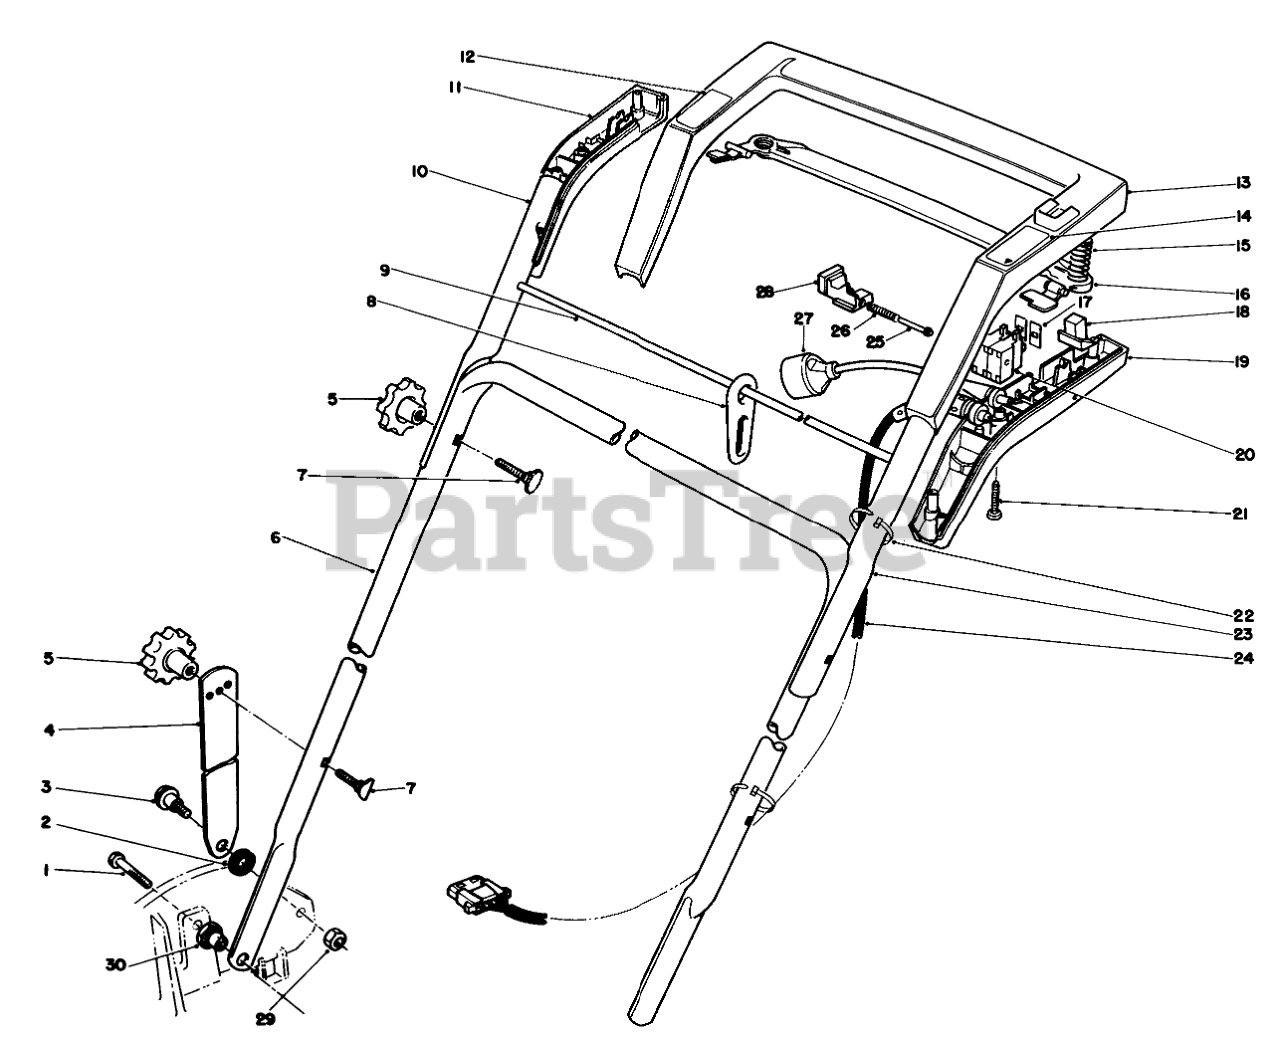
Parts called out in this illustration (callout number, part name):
1	SCREW-HH
2	SPACER
3	SCREW-SHOULDER
4	Handle Latch
6	LOWER HANDLE
7	5/16-18 X 2 HNDLE SCREW
8	CORD MINDER
9	CORD MINDER ROD
10	UPPER HDLE TUBE RH
11	RH GRIP COVER
12	Decal-Handle, Warning
13	Grip-Handle (Incl. Ref. #12 & 14)
14	ON/OFF DECAL
15	COMP SPRING
16	SQUEEZE LEVER
17	DUST COVER
18	SWITCH BUTTON
19	LH GRIP COVER
20	ON/OFF SWITCH
21	SCREW-PPH
22	Cable Tie
23	UPPER HDLE TUBE LH
24	WIRE HARNESS
25	BUTTON GUIDE
26	COMPRESSION SPRING
27	POWER SUPPLY CORD
28	INTERLOCK BUTTON
29	NUT-LOCK, NI
30	HANDLE PIVOT NUT
